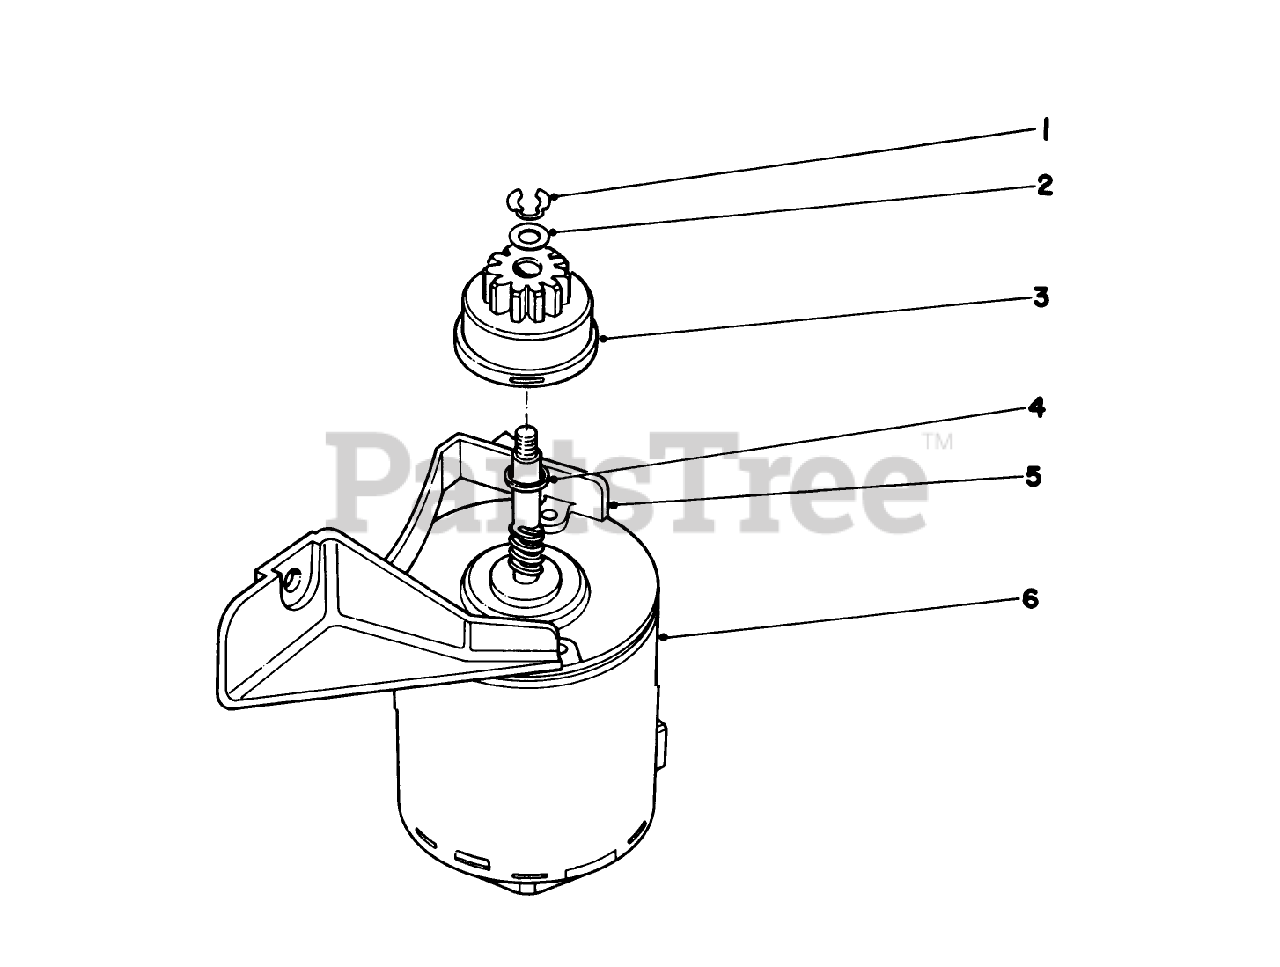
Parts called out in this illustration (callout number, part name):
1	Retaining Ring
2	WASHER
5	Mounting Bracket
